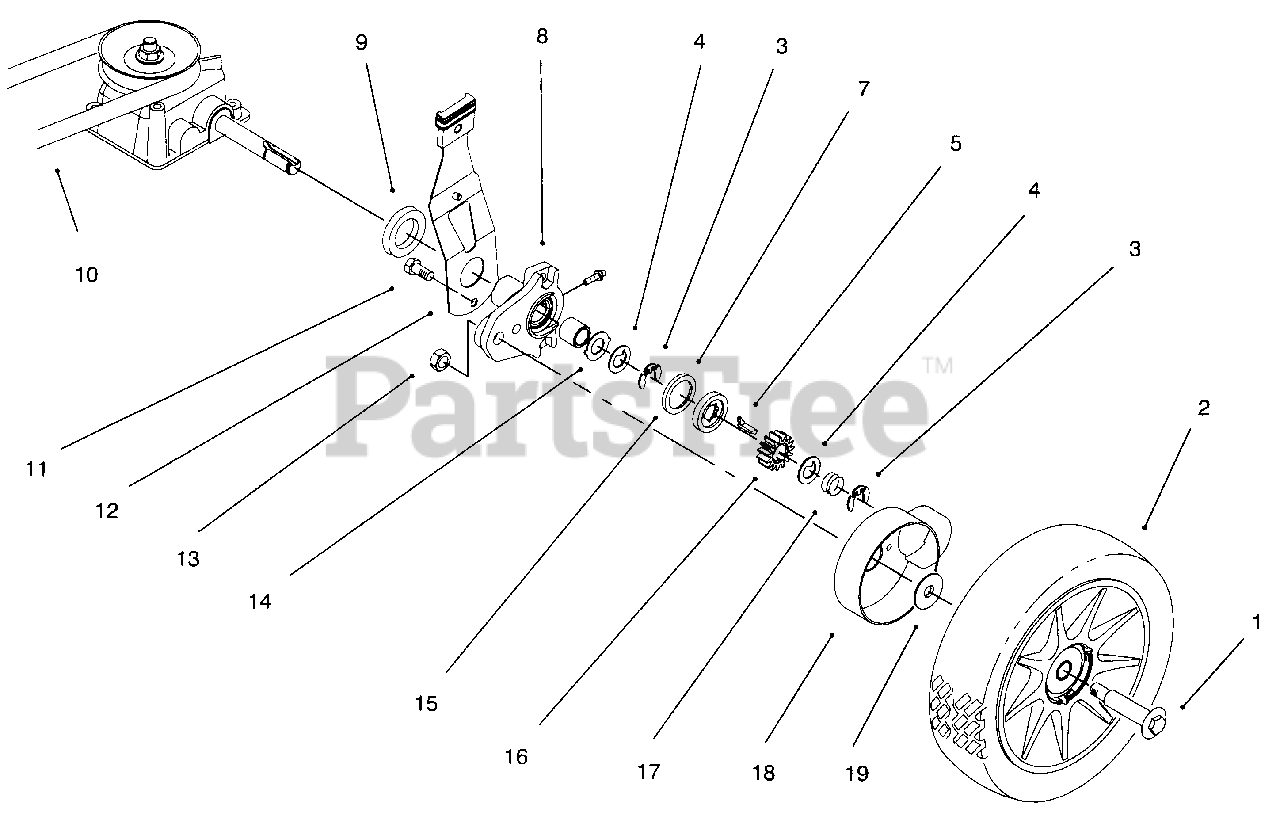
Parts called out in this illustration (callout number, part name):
1	Bolt-Shoulder
2	Wheel & Tire Ass'y 8"
3	Ring-Retaining
4	Washer-Thrust Keyed
5	Key-Rocking L.H.
7	Ring-Friction
8	Height Adj. Arm-Rear
9	Spacer-Axle Shaft
11	Screw-Hex Hd.
12	Spring Arm Ass'y
13	Nut-Lock
14	Washer-Thrust
16	Gear-Pinion
17	Spring-Compression
18	Cover-Wheel
19	Washer-Stepped
